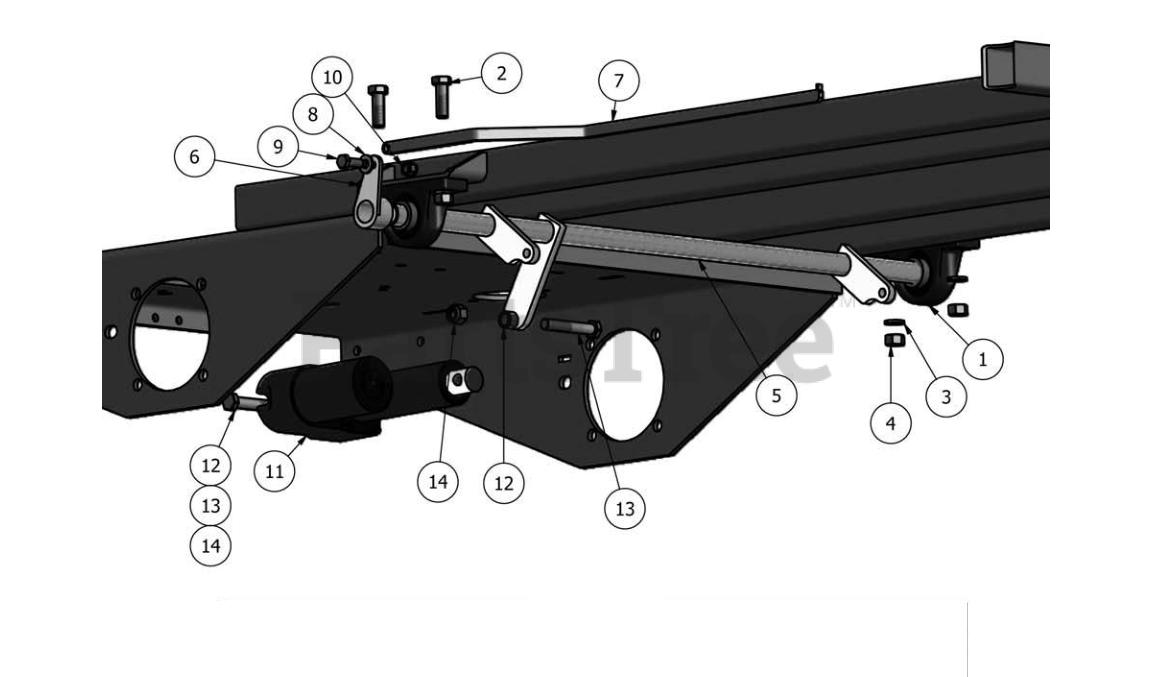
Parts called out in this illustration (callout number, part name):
1	1" Pillow Block
2	1/2" x 1 1/2" Hex Bolt
3	1/2" Lock Washer
4	1/2" Hex Nut
5	Actuator Bar
6	Height Indicator Lever
7	Pup Height Indicator
8	.360 ID Plastic Washer
9	3/8" x 1" Hex Bolt
10	3/8 Nylock Nut
11	Electric Actuator
12	1/2" Flat Washer
13	1/2" x 3" Hex Bolt
14	1/2" Nylock Nut
